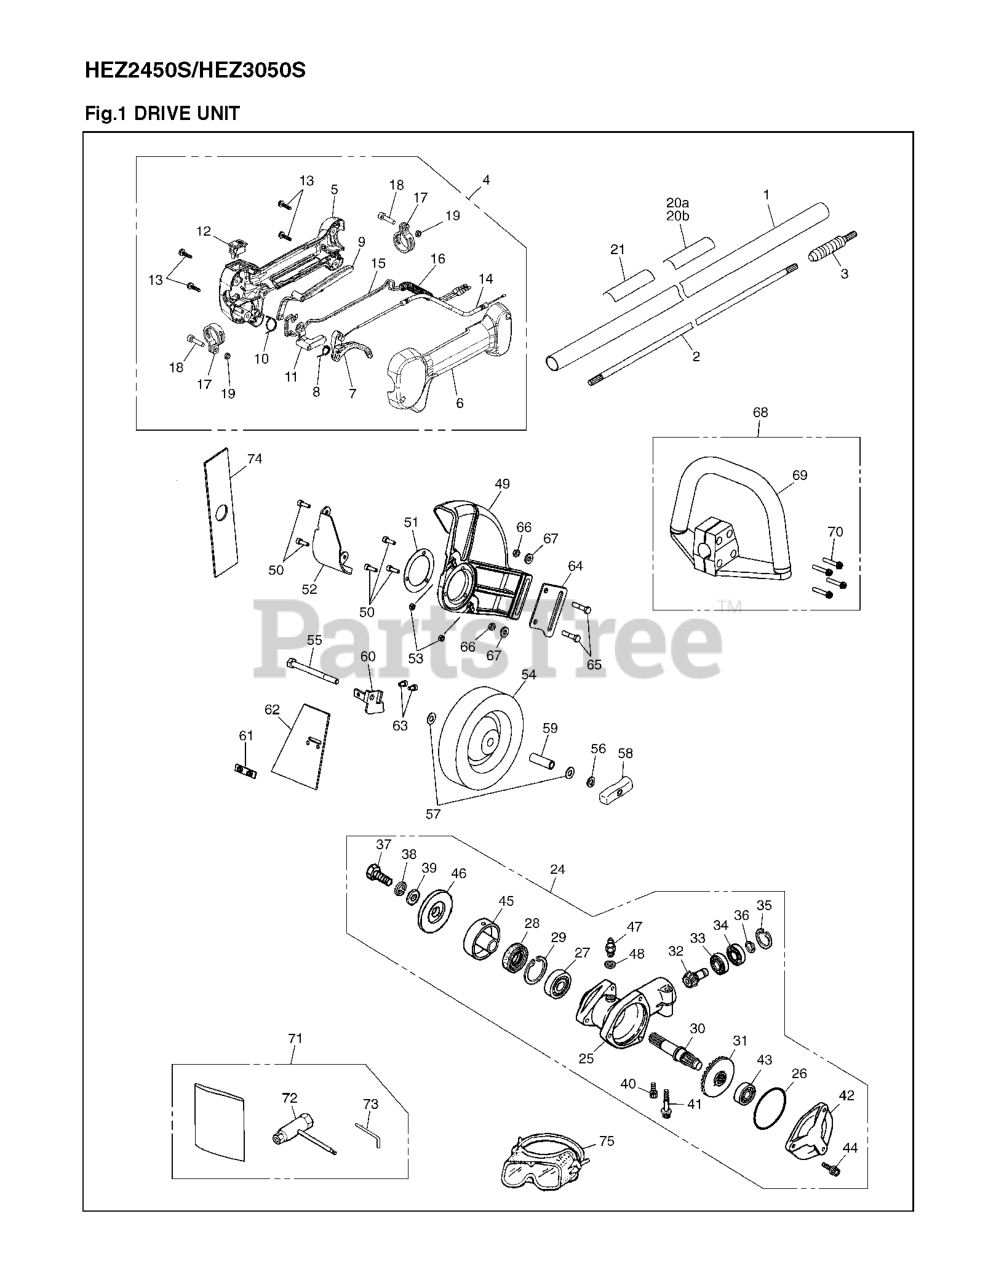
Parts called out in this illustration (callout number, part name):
1	PIPE COMP (RPLS 848A475820)
2	DRIVE SHAFT (BCZ2601S)
3	JOINT COMP
5	BODY-R
6	BODY-L
7	LEVER, THROTTLE
8	SPRING, THROTTLE
9	LEVER FOR GRIP (RPLS -0600)
11	LEVER JOINT
15	CORD - C
19	NUT
21	LABEL CAUTON FOR BC
24	GEARCASE ASSY
25	GEARCASE
28	OIL SEAL
37	BOLT M8 X L25 L/H
40	BOLT, M5 x 12
44	BOLT M5 X L14 ALLEN
45	HOLDER(A)
46	HOLDER (B)
49	GUARD
50	BOLT M5 X L16 ALLEN
52	PROTECTOR
55	BOLT
63	BOLT M5 X L10 ALLEN BOLT
64	MAIN BRACKET
65	BOLT
68	HANDLE ASSY. (RPLS T319514001)
69	HANDLE T
71	TOOL SET
75	GOGGLExxx (RPLS
